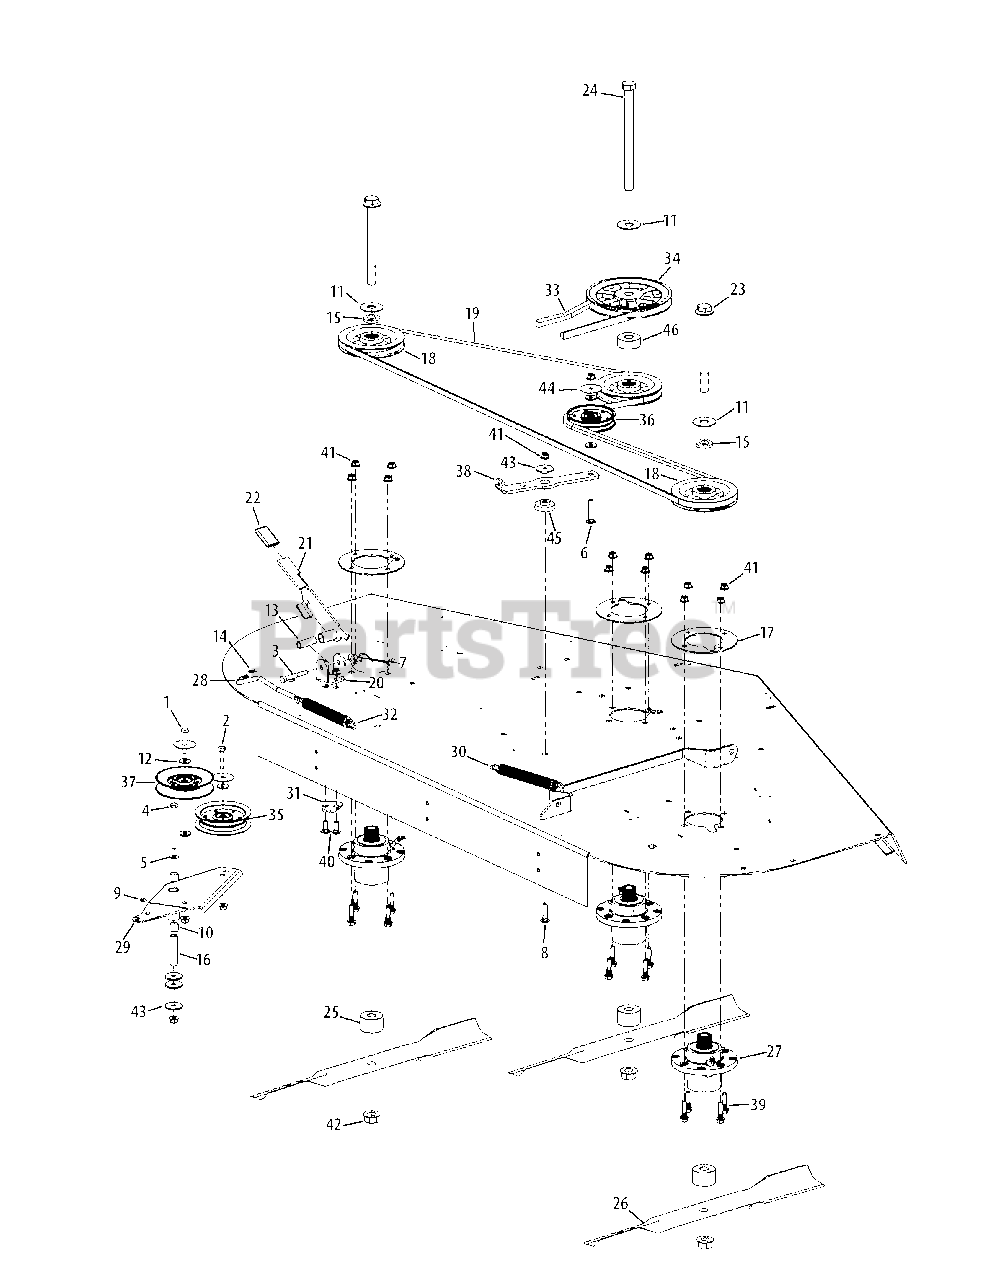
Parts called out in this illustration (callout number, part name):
1	Hex Screw, 3/8-16 x 2.00
2	Hex Screw, 3/8-16 x 1.75
3	Hex Screw, 3/8-16 x 2.50
4	Hex Screw, 3/8-16 x 4.00
5	Washer, .406 x .813 x .063
6	Carriage Bolt, 3/8-16 x 2.00
7	Flange Counter Lock Nut, 3/8-16
8	Carriage Bolt. 3/8-16 x 1.50
9	Grease Fitting, 1/4-28
10	Sleeve Bearing, .628 x.753 x.625
11	Washer, .781 x 2.00 x .105
12	Washer, .406 x 1.00 x .105
13	Spacer, .390 x .630 x 1.75
14	Hair Pin, 1/8 x 1.125 x .072
15	Spacer, .812 x 1.47 x .218
16	Spacer, .390 x .635 x 2.75
17	Spindle Support Plate
19	V-Belt
20	Idler Tension Bracket
21	Tension Handle Weldment
22	Idler Tension Handle Grip
23	Hex Screw, 3/4-16 x 7.50
24	Hex Screw, 3/4-16 x 9.50
25	Spacer, .760 x 2.00 x 1.28
26	Blade, 25"
27	Spindle Assembly
28	Tensioner Spring Rod
29	Idler Double Weldment
30	Extension Spring, .94 x 7.57 x .14
31	Idler Spring Bracket Adapter Plate
32	Extension Spring, .94 x 7.74 x .14
33	V-Belt
35	Idler Pulley
36	Idler Pulley
37	Idler Pulley
38	Deck Idler Arm
39	Flange Bolt, 3/8-16 x 1.5
40	Carriage Bolt, 3/8-16 x 1.00
41	Flange Lock Nut, 3/8-16
42	Flange Lock Nut, 3/4-16
43	Flat Washer, .390 x 1.500 x .134
44	Flat Washer, .406 x 1.92 x .060
45	Shoulder Spacer, .854 x .280
46	Spacer, .760 x 2.000 x .790
